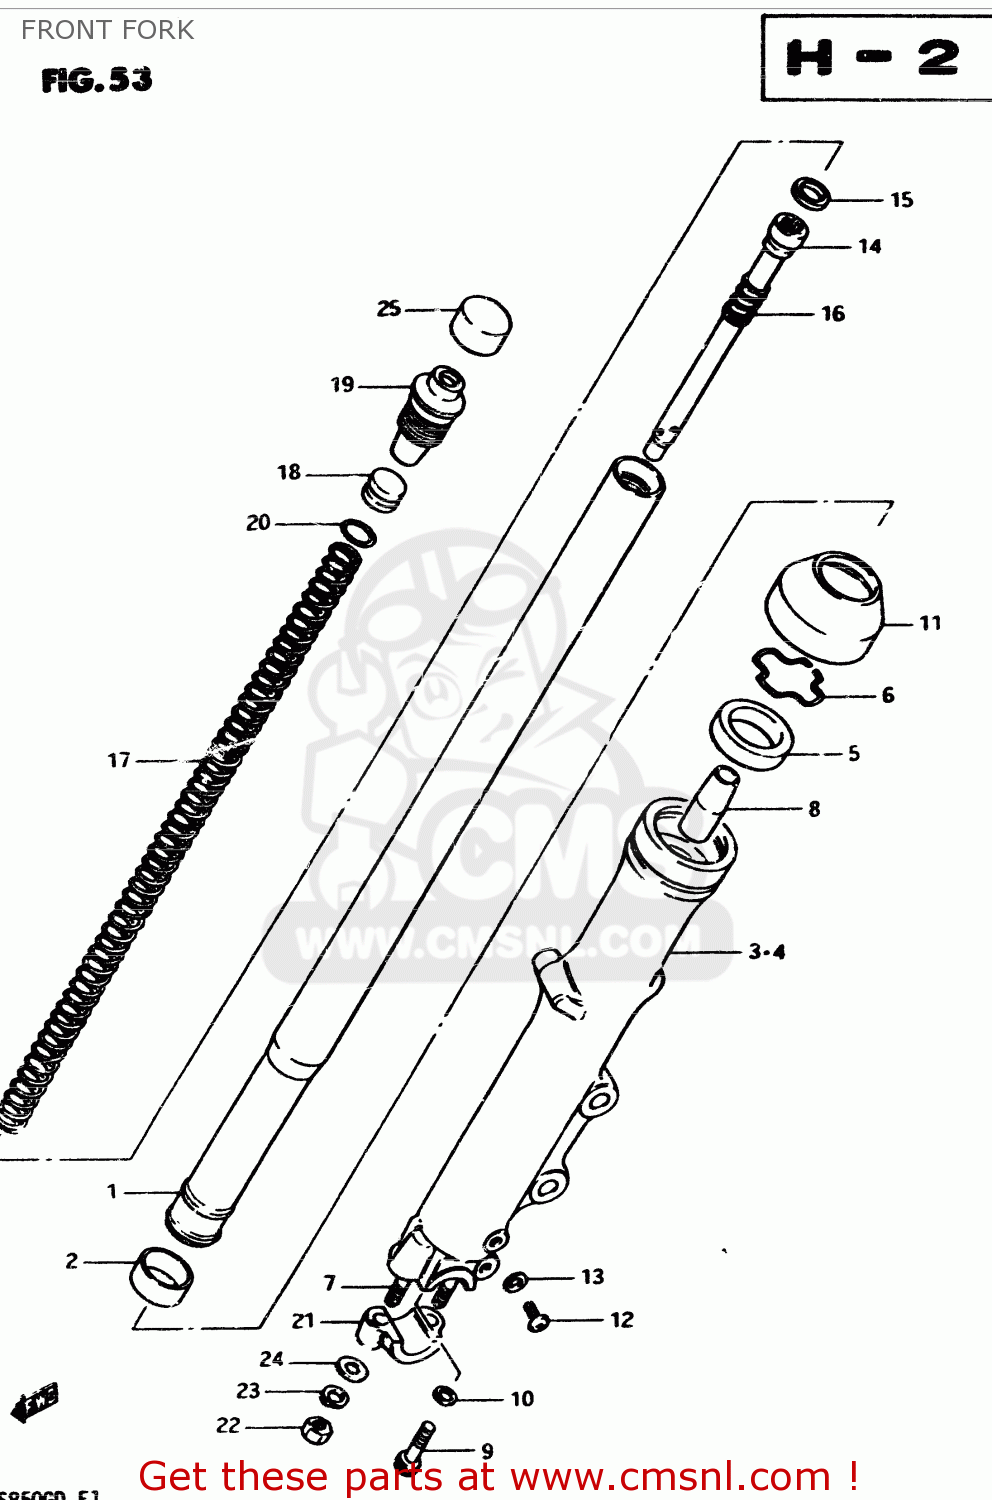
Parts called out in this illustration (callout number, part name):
1	TUBE,FORK,INNER
2	PISTON
3	TUBE,FORK,OUTER,RIGHT
4	TUBE,FORK,LEFT,OUTER
5	OIL SEAL,FRONT FORK
6	RING,STOPPER
7	STUD BOLT
8	PIECE,OIL LOCK
9	BOLT,FORK CYLINDER(10X25)
10	GASKET (NAS)
11	SEAL,DUST
12	SCREW
13	GASKET,DRAIN,PLUG (NAS)
14	CYLINDER,FRONT FORK
15	RING,PISTON
16	SPRING,REBOUND
17	SPRING,FRONT FORK
18	PISTON,FREE
19	CAP
20	O-RING
21	HOLDER,AXLE
22	NUT (8MM)
23	LOCK WASHER
24	WASHER
25	CAP,RUBBER
